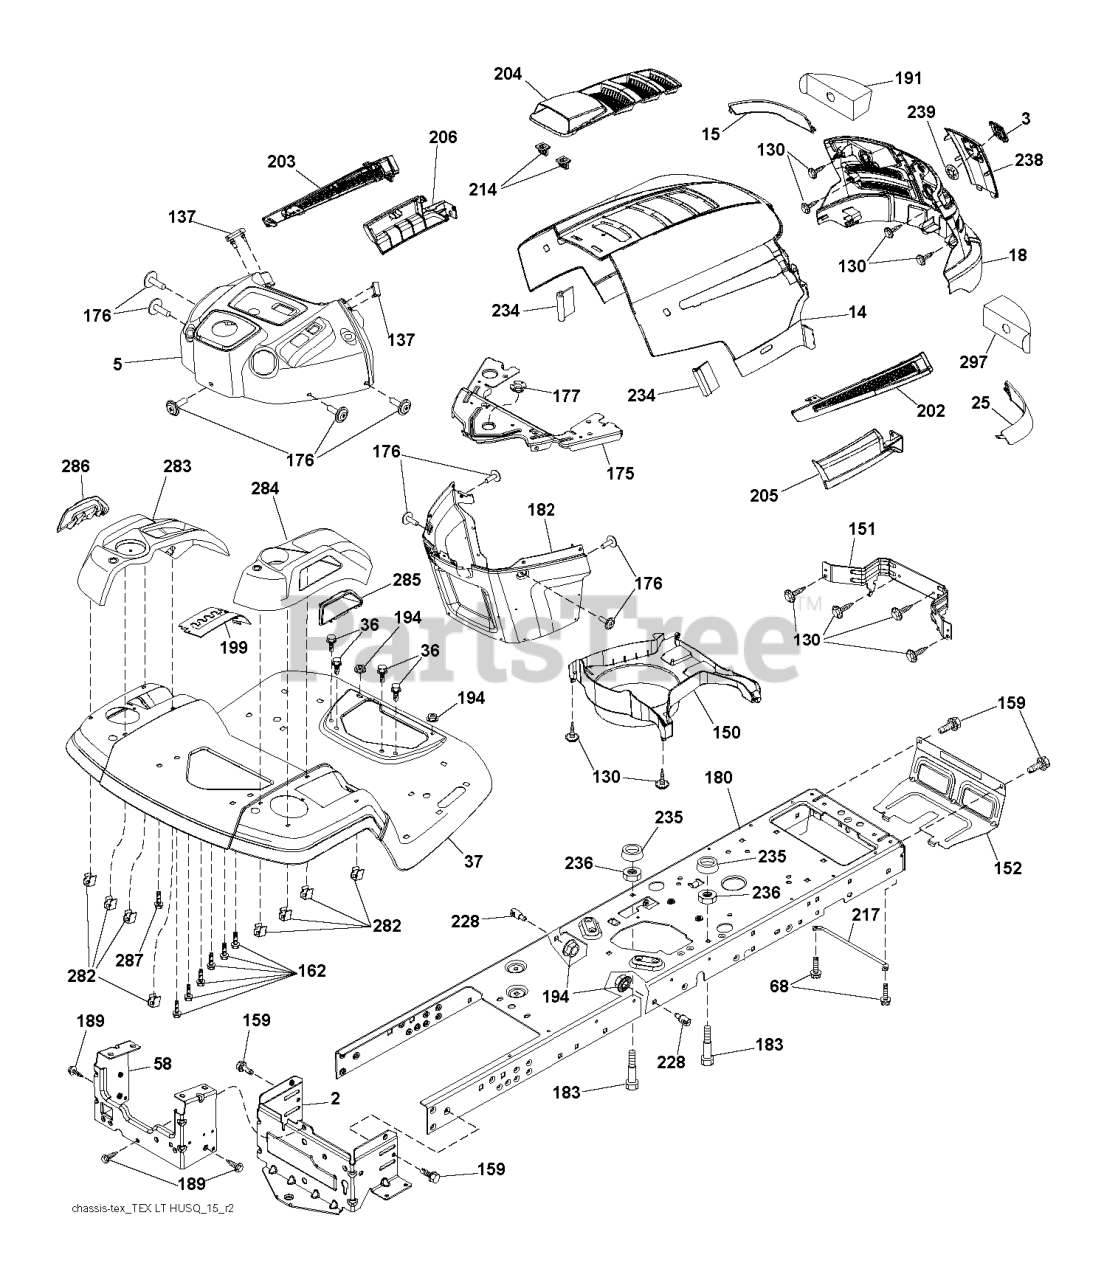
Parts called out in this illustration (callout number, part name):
2	DRAWBAR.LOWER.2PC.18/22
3	RP LOGO
5	DASH
14	HOOD
15	LENS.HUSQVARNA LT.LH
18	GRILLE.SVC.HUSQVARNA.LT.GREY
25	LENS.HUSQVARNA LT.RH
36	SCREW 5/16"
37	RP FENDER.TLT.FS.W/CPH.422
58	DRAWBAR UPPER 2PC SMALL FENDER
68	Screw 5/16-18 x 1/2 Hex, Self Tapping 5/16-18 x 1/2
130	SCREW.#10 X 0.750.BOS
137	BUMPER DASH
151	BRACKET PIVOT
152	SHIELD.BROWNING/DEBRIS
159	SCREW, 3/8-16X3/4
162	SCREW.HI-LO.CONSOLE
175	CROSSMEMBER
176	SCREW.#10-24X5/8.RN.QU
177	BUSHING STEERING
180	CHASSIS.STAMPING.LT/GT
182	DASH.LOWER.PREDATOR LT
183	BOLT.5/16-18X1-1/4 FULL.THREAD
189	SCREW
191	INSERT REFLECTIVE
194	NUT LOCK HEX FLANGE 5/16-18
199	PLATE.DECK.LIFT.HUSQ.LT
202	VENT SIDE HOOD LH
203	VENT SIDE HOOD RH
204	VENT TOP HOOD
205	SKIRT SIDE RH
206	SKIRT SIDE LH
214	CLIP.RETAINER.TINNER.
217	ROD.PIVOT.HOOD
228	STUD.FASTNER.W/ANTI-ROTATE
234	BUMPER.HOOD.TEX.HUSQVARNA
235	SPACER FENDER
236	NUT.CENTERLOCK.5/16-
238	TRIM
282	CLIP.RETAINER.CONSOLE.LT.HUSQ
283	CONSOLE.ASM.LFT.NFR.HUSQ.LT
285	CONSOLE INSERT RH
286	CONSOLE.INSRT.LH.HUSQ.LT.BLACK
287	SCREW 1/4X20
297	INSERT.REFLECTIVE.RH.
